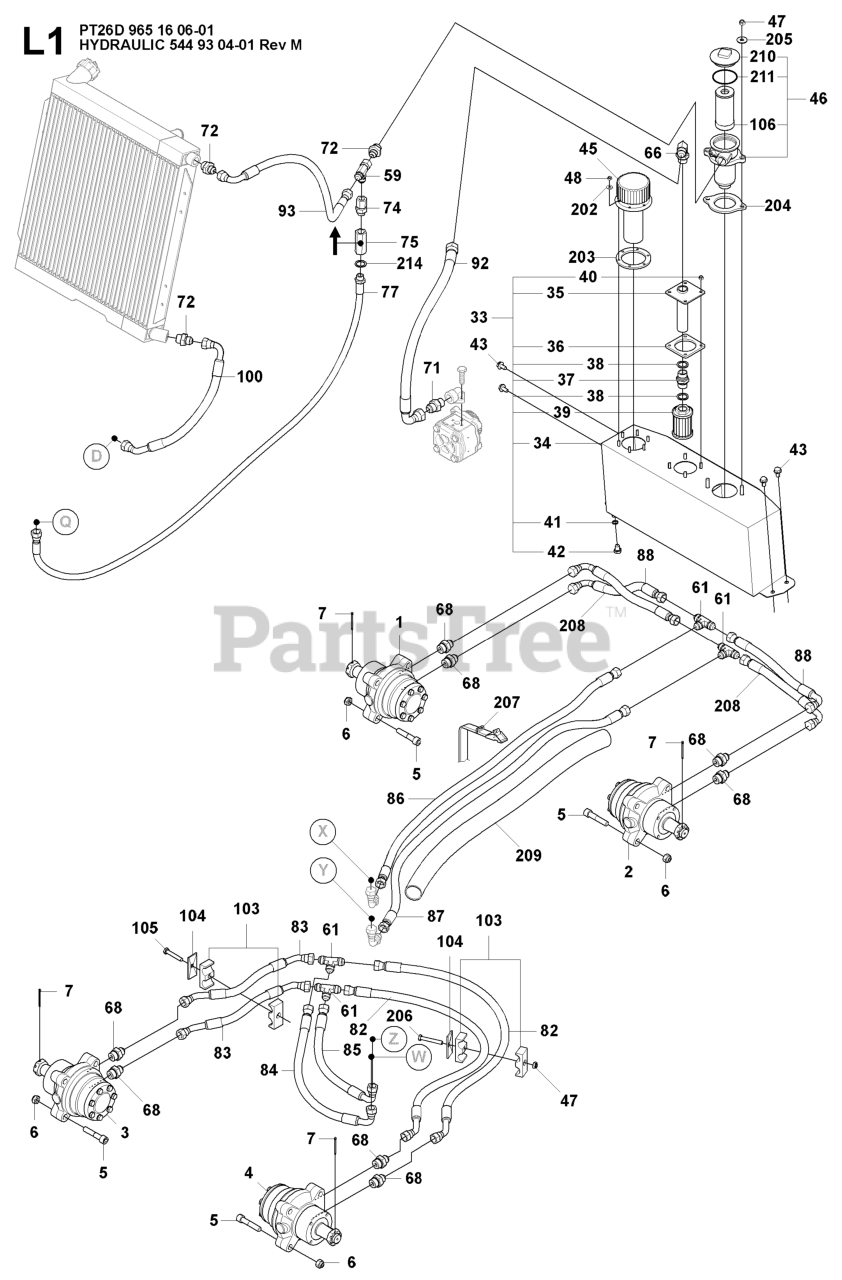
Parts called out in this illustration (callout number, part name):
1	WHEEL MOTOR 125 CW
2	WHEEL MOTOR 125 CCW
3	WHEEL MOTOR 160 CW
4	WHEEL MOTOR 160 CCW
7	COTTER PIN
37	PIPE FITTING G STRAIGHT 1/2-1/
39	FILTER PUMP SUCTION, AWD
40	LOCKNUT M6
41	GASKET 14X10.5X1 COPPER
42	SCREW EHHM
46	FILTER HOLDER
47	LOCKNUT M8
48	LOCKNUT M5
74	PIPE FITTING JIC-BSPP STRAIGHT
75	CHECK VALVE 2BAR
105	BOLT FLANGE - M8X50
202	WASHER
205	WASHER BRB 8.4X17
209	HOSE GUARD D=43 L=750
